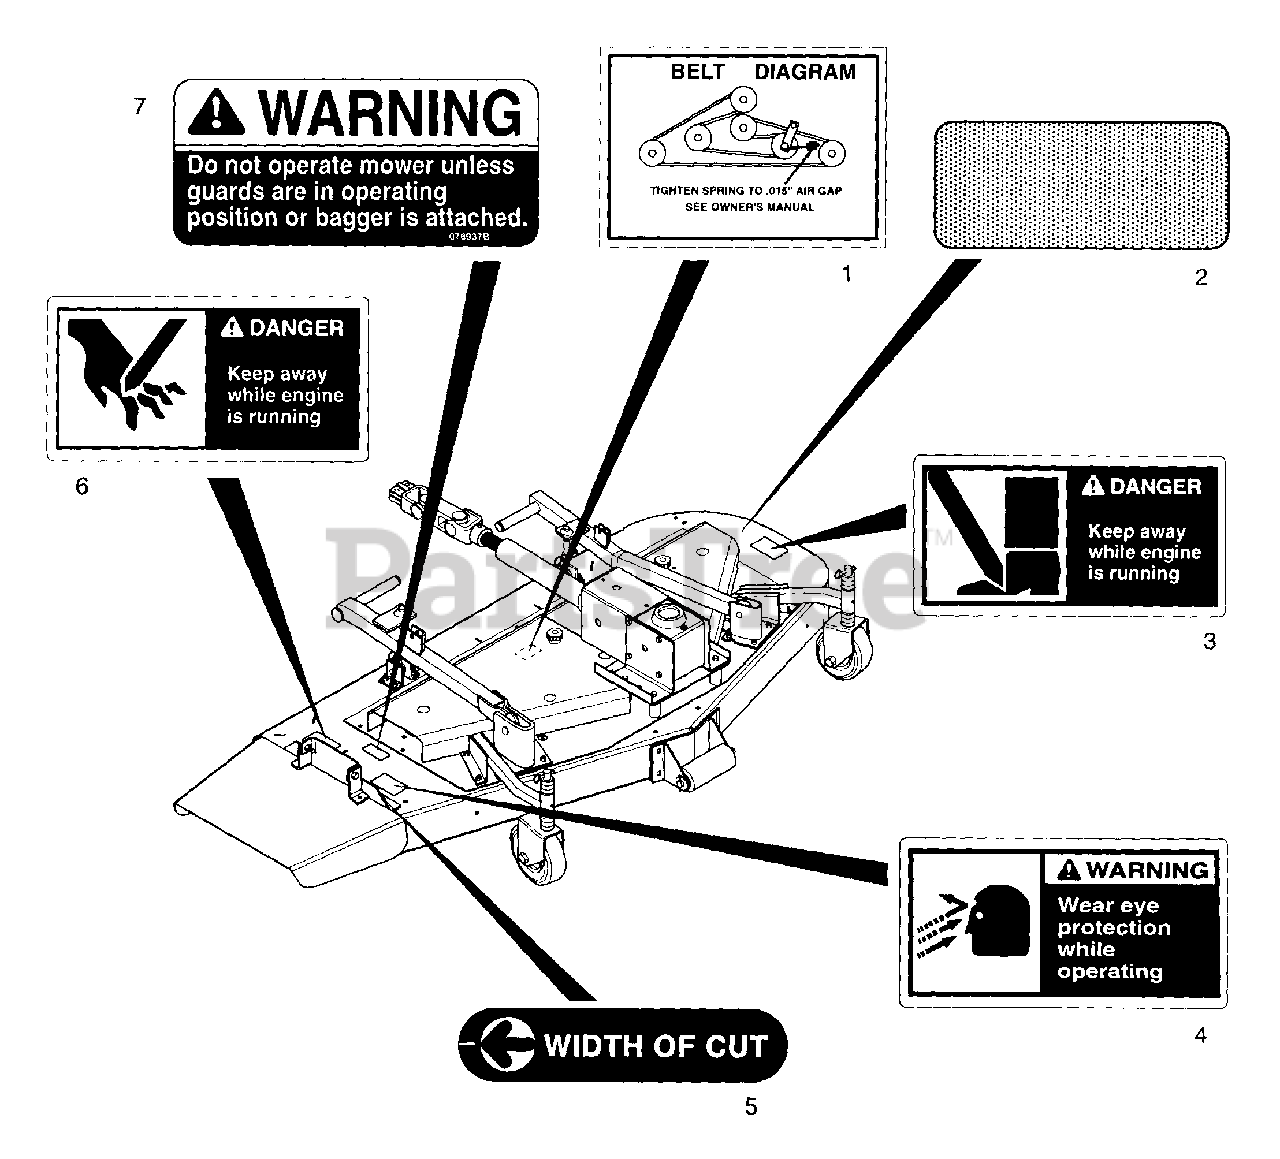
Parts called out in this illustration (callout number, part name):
1	Decal, Belt Diagram
2	Cover, Large Footboard (005,006,301,302)
3	Decal, Danger Foot
4	Decal, Warning Eye
5	Decal, Width of Cut
6	Decal, Danger Hand
7	Decal, Warning
